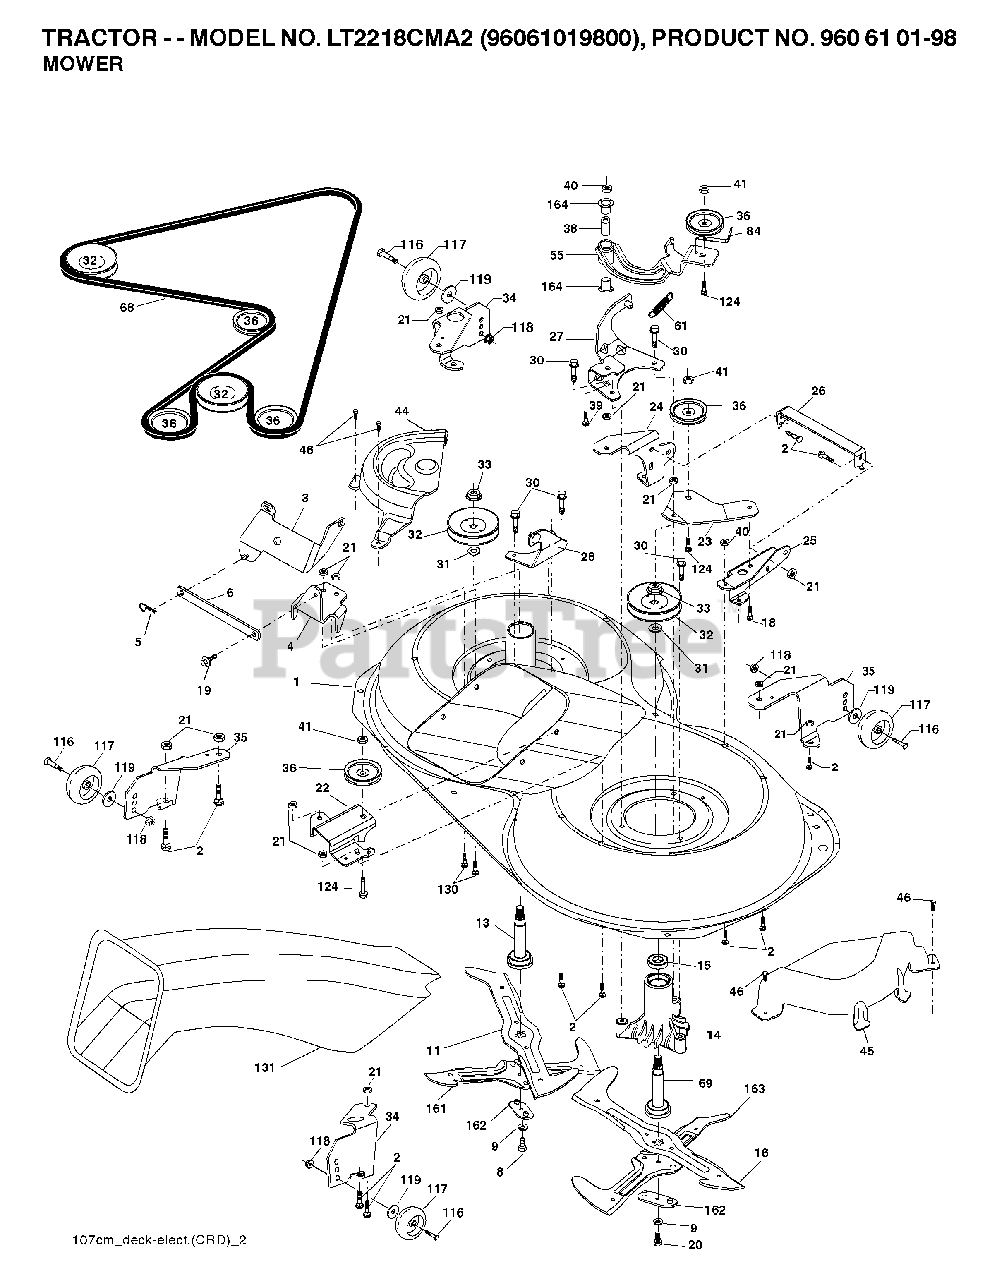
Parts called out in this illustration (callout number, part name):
2	BOLT
3	BRACKET
5	RETAINER-SPRNG RB
6	BAR SWAY
9	LOCKWASHER
11	BLADE.3N1.LH.CRD
13	SHAFT ASM VENT
14	HSG MANDREL
16	BLADE.3N1.RH.CRD
19	BOLT SHD 5/16-18
21	LOCKNUT
22	BRACKET
23	BRACKET
27	BRACKET
30	SCREW, WASHER HEAD
31	WASHER.SPACER.MANDREL
33	NUT.FLANGE.LOCK.TOP
36	PULLEY.IDLER.4.25
40	LOCKNUT
41	NUT LOCK FLG 3/8-16 UNC
45	MANDREL COVER
46	SCREW.1/4-20X5/8
55	ARM IDLER
68	HEX-BELT 107 MOWER
69	SHAFT.ASM.W/LWR.BRG.RH.THREAD
84	KEEPER, BELT IDLER
116	BOLT.SHOULDER.3/8-16X3-5/8
117	WHEEL. GUAGE RALLY
118	NUT LOCK FLG 3/8-16 UNC
124	BOLT.3/8-16X1.50
131	CHUTE BAGGER
164	BRNG T
